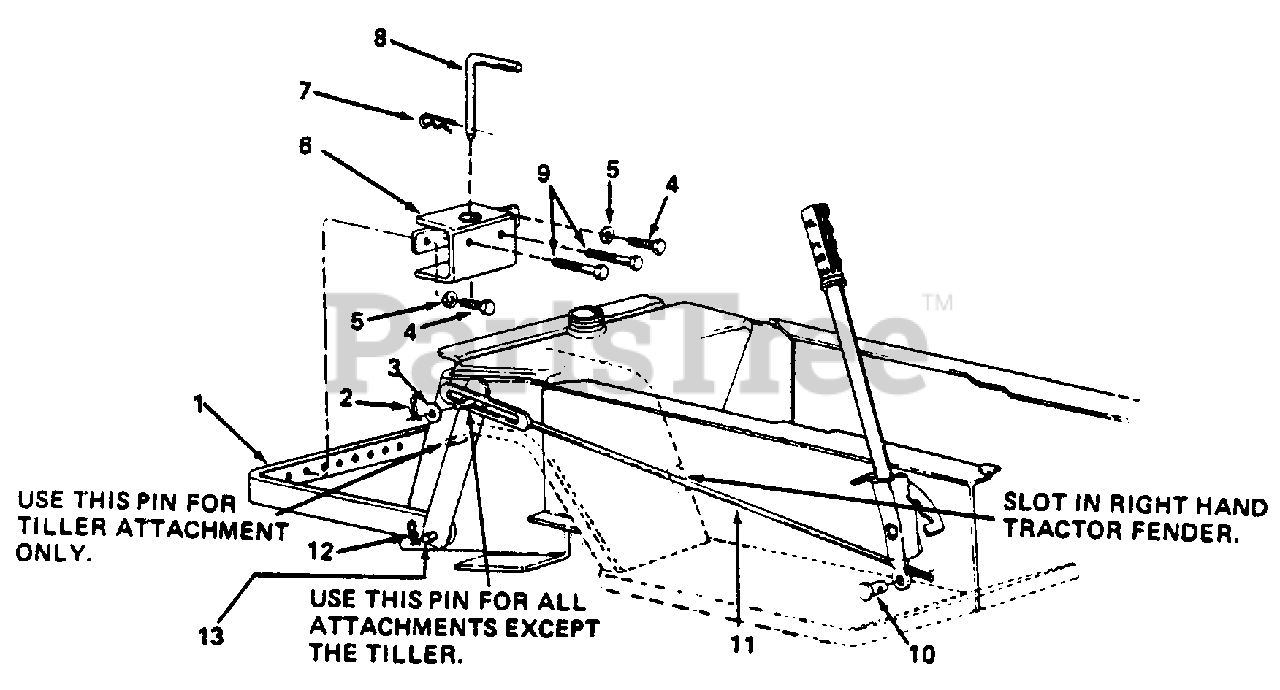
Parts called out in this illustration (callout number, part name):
3	Fl.-Wash. 1/2 I.D.
4	Hex Scr. 1/2-13 x l.00 Lg.
5	L-Wash. 1/2 Scr.
8	Hitch Pin
9	Hex Scr. 1/2-13 x 3.00 Lg.
10	Adjustment Ferrulle
13	Hitch Rod
